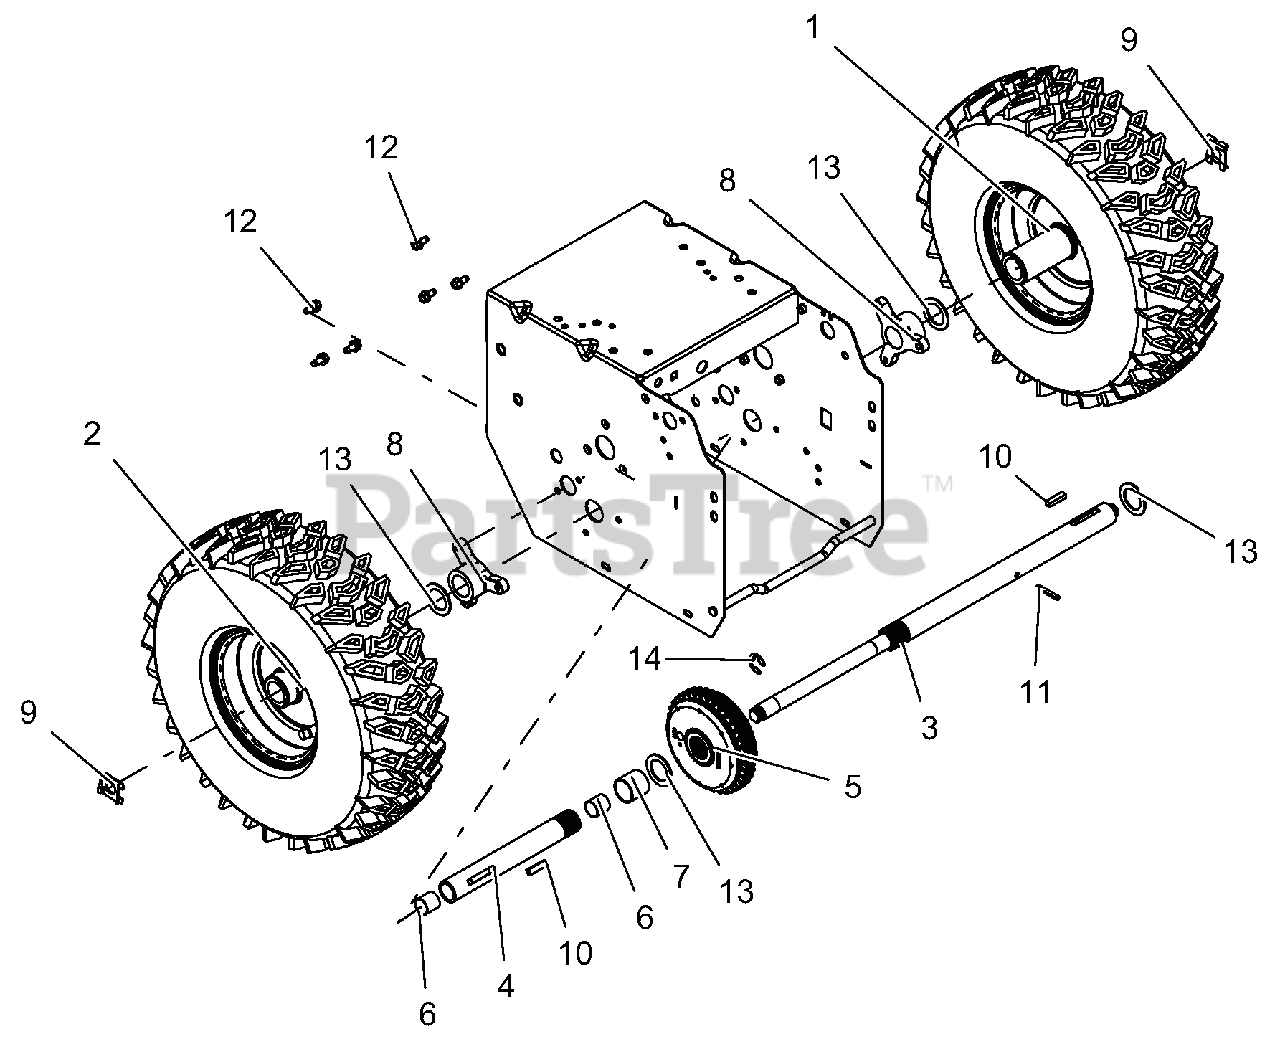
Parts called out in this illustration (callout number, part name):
1	TIRE/WHEEL,LH 15X5.00-6 REMOTE
2	TIRE/WHEEL,RH 15X5.00-6 REMOTE
3	AXLE, LONG - DIFFERENTIAL
4	AXLE, SHORT - DIFFERENTIAL
5	DIFFERENTIAL, AUTOMATIC
6	BSHG-SLV .706X.764X.75 BRZ
7	BSHG-SLV, 1.012X1.125X1.00
8	BUSHING, AXLE
9	CLIP, SNAP .625 DIA
10	KEY-RECT .25X.188X1.00
11	PIN-ROLL .188X1.25
12	SCR-TAP .25-20X.50 HWH TR YWZ
13	WSHR-FL-STL 1.010X1.505X.062YZ
14	RG-RTNG-EXT .625X.042
